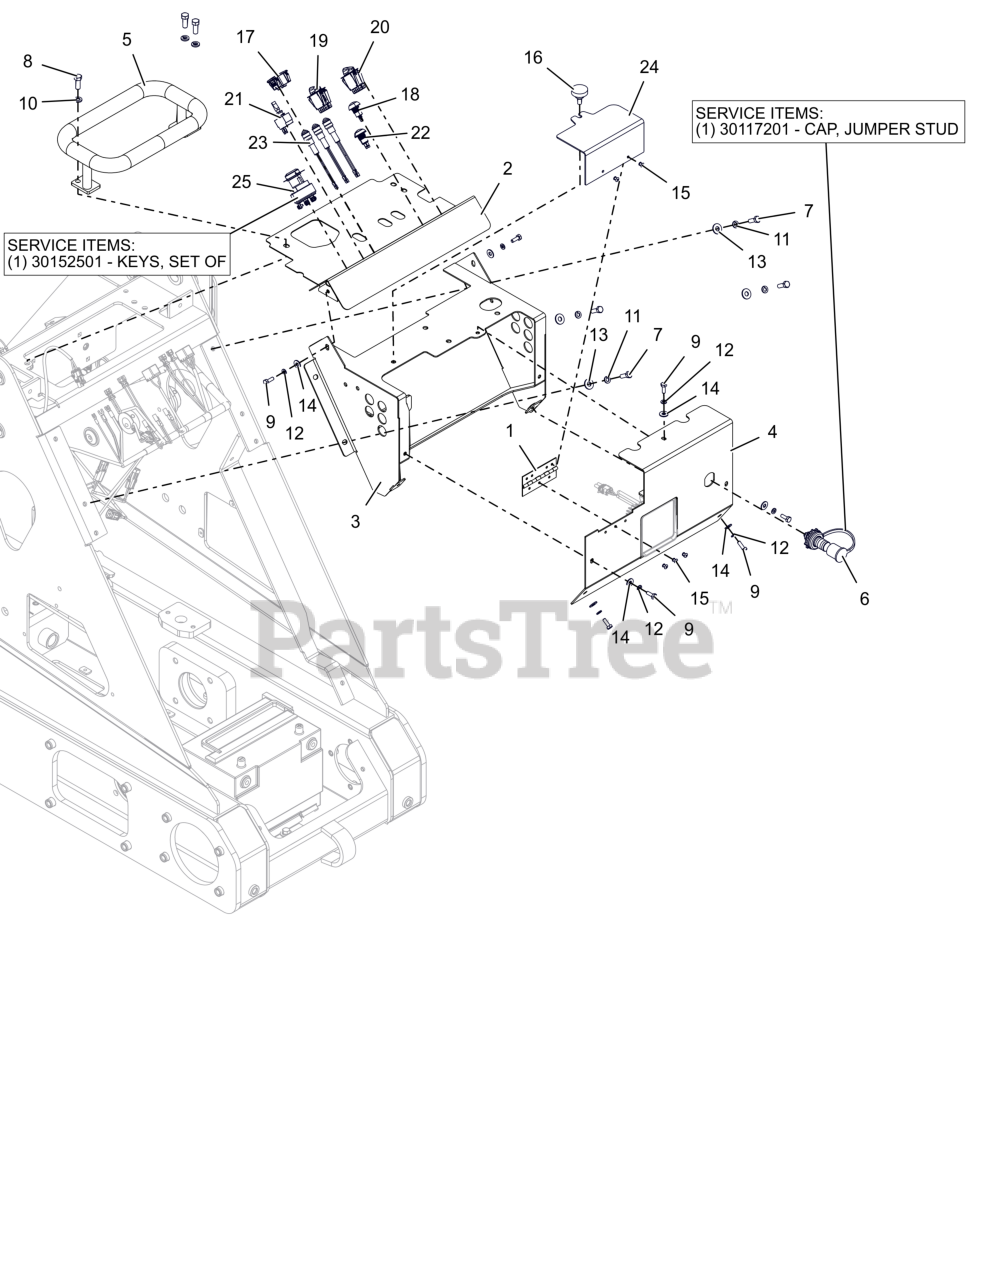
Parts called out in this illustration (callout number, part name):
2	PANEL, CNTRL - W/SAFETY DECAL
3	MOUNT, FRONT (BLACK)
4	COVER, FRONT (BLACK)
5	HANDLE, PADDED
6	STUD, JUMPER, POS
6	CAP, JUMPER STUD
7	BLT,HEX .31-18X1.00 G5 ZCC
8	BLT,HEX .38-16X1.00 G5 ZCC
9	BLT, HEX .25-20X.75 G5 ZCC
10	WSHR,LK-REG .375X.094 ZCC
11	WSHR,LK-REG .312X.078 ZCC
12	WSHR,LK-REG .250X.062 ZCC
13	WSHR,FLT .375X.875X.083 ZCC
14	WSHR, FLT .312X.734X.065 ZCC
15	RVT-POP .187X.402 DOME ST
16	KNOB, W/ STUD 5/16" 18 X 3/4
17	HOUR METER
18	SWITCH, MOMENTARY - N/O GREEN
19	SWITCH, ROTARY - SPST
20	SWITCH, ROTARY - SPDT
21	SWITCH, TOGGLE SPST
22	SWITCH, MOMENTARY-ACTION RED
23	LIGHT- INDICATOR
24	COVER, ACCESS - W/SAFETY DECALS
25	SWITCH, IGNITION (W/KEYS)
25	KEYS, SET OF 2
